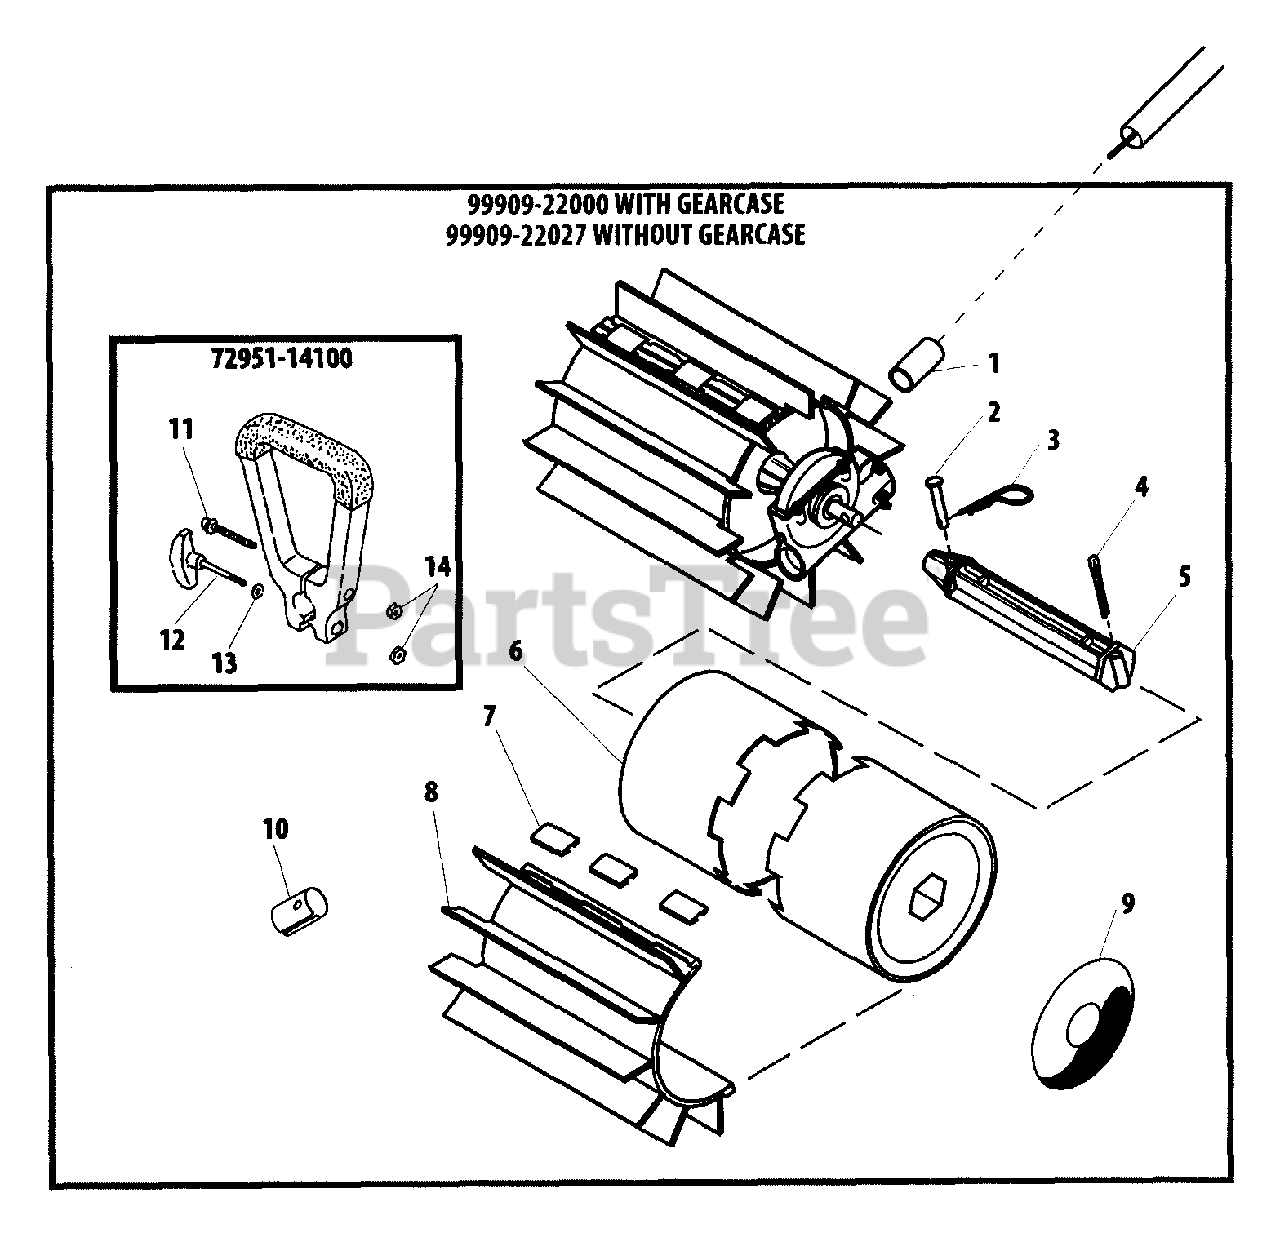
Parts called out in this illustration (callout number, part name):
1	CAP, MAIN PIPE
2	PIN - CLEVIS
3	PIN - HITCH
4	PIN, SPLIT
5	AXLE
6	HUB, DRUM
7	CLIP, BELT
8	BELT
10	SPACER
11	SCREW
12	THUMBSCREW
13	WASHER
14	NUT - 6
72951-14100	HANDLE ASSY
99909-22000	B & D WITH GEARCASE
99909-22027	B & D WITHOUT GEARCASE
